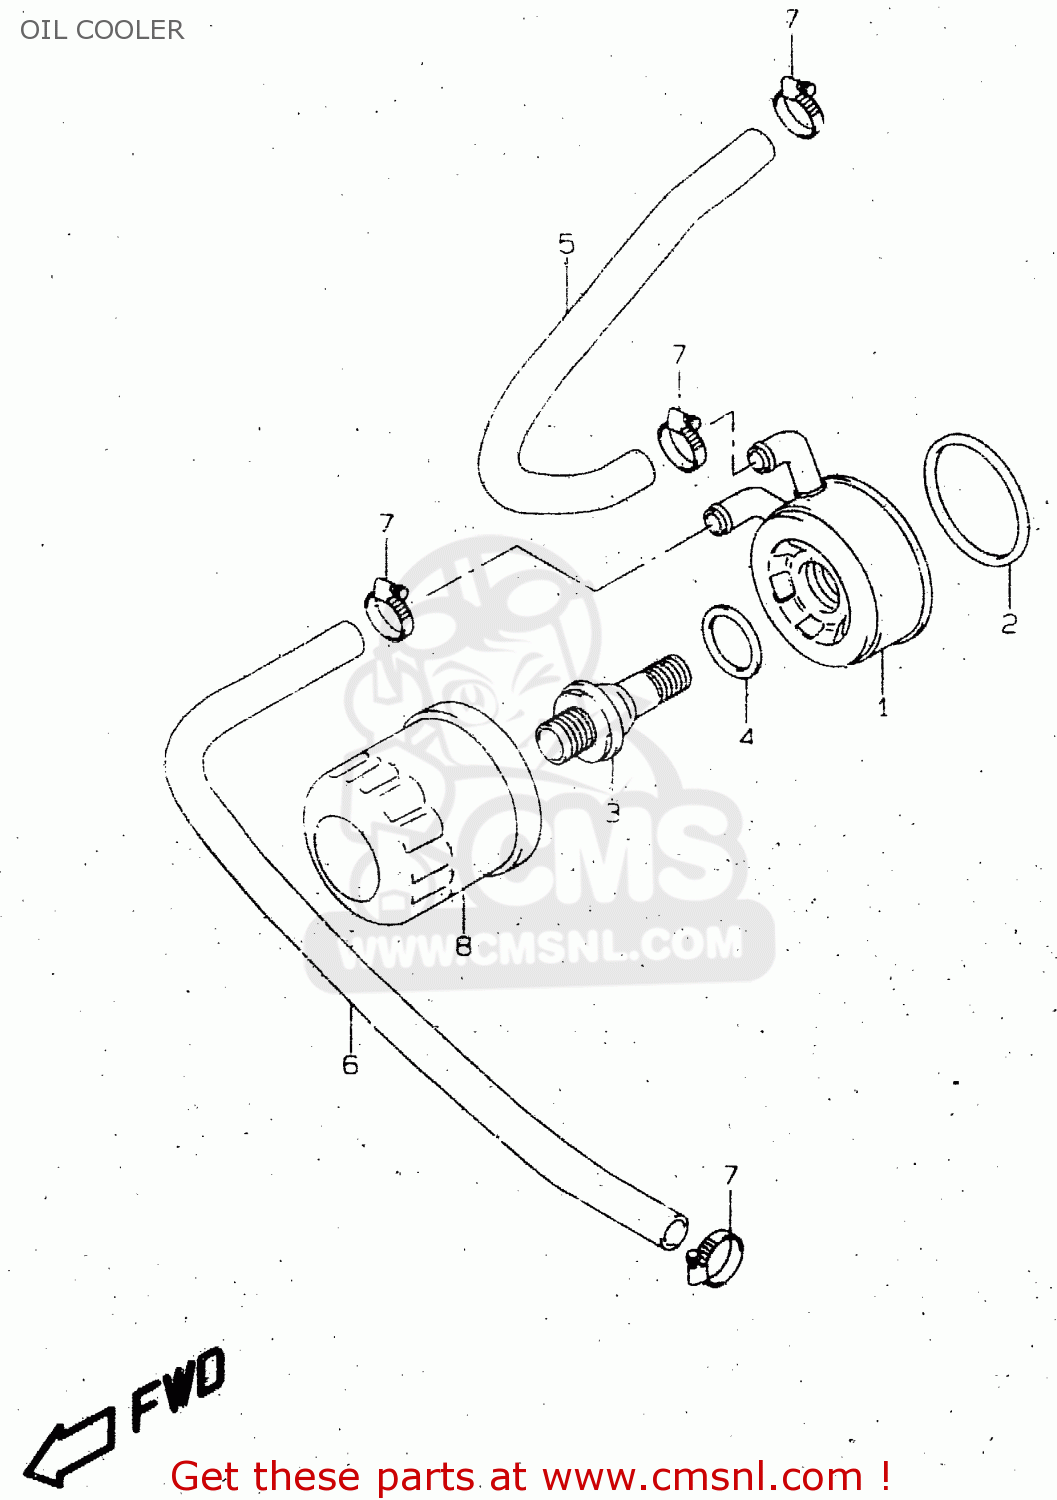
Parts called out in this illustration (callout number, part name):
1	COOLER ASSY,OIL
2	O RING(D:3.1,ID:63.9)
3	BOLT,OIL COOLER UNION
4	SHIM(25X34X0.7)
5	HOSE,OIL COOLER INLET
6	HOSE,OIL COOLER OUTLET
7	CLAMP
8	FILTER ASSEMBLY,ENGINE OIL
